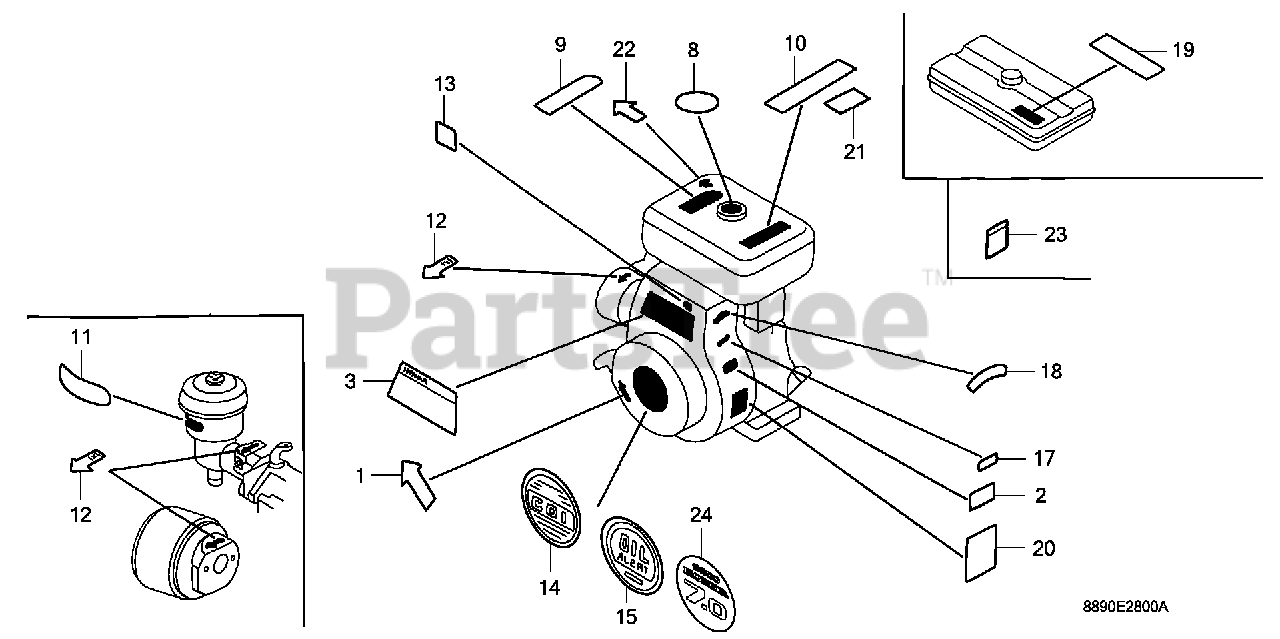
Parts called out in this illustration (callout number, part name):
1	MARK, STARTING (NOT AVAILABLE)
3	EMBLEM (ENGLISH/FRENCH/SPANISH)
3	EMBLEM (ENGLISH/FRENCH/SPANISH) (NOT AVAILABLE)
9	MARK, CAUTION (ENGLISH/FRENCH/SPANISH)
12	MARK, CHOKE
14	MARK, C.D.I.
20	MARK, OIL CAUTION
